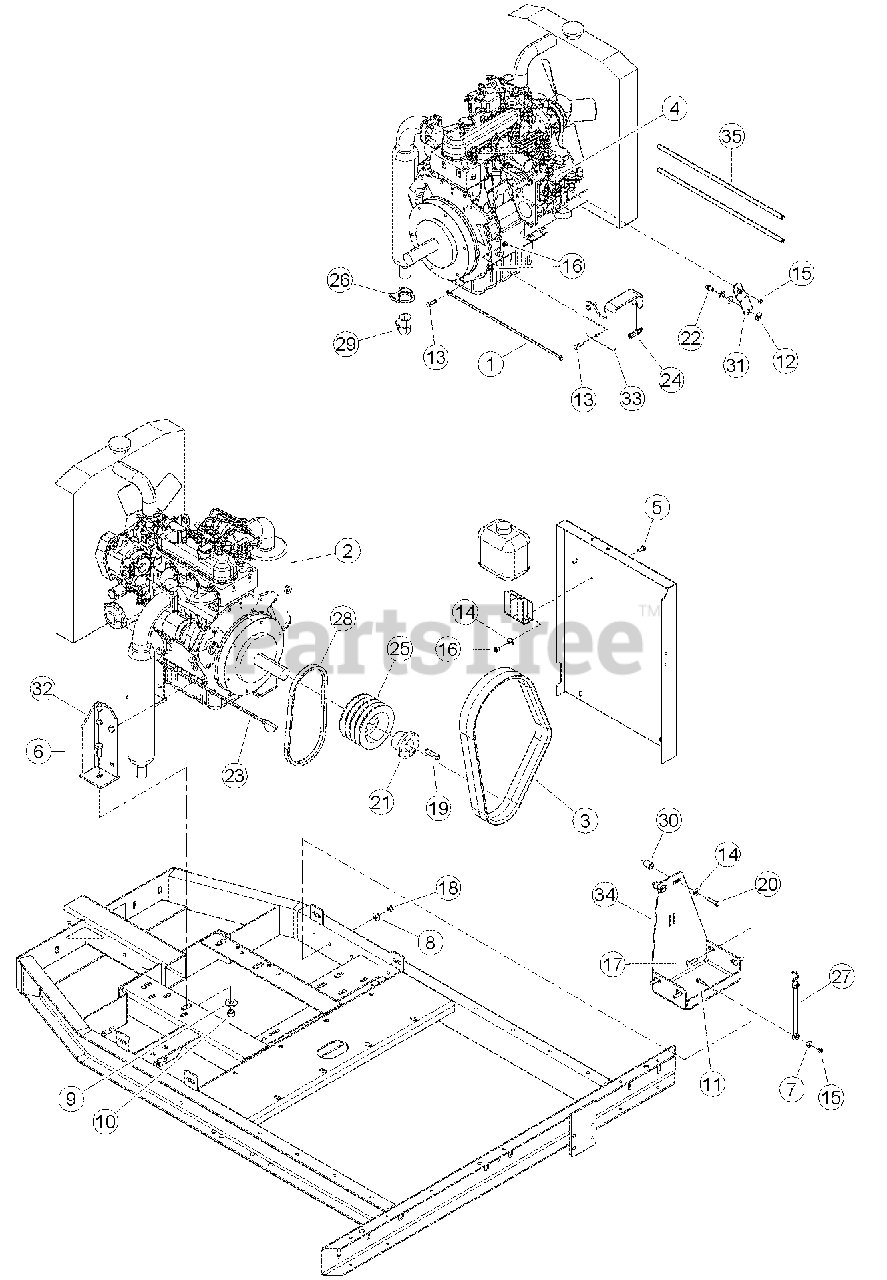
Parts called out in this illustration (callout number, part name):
1	CABLE, 18" NEG (R / R)
2	ENGINE, 1105B KUBOTA DIESEL (FOR SERVICE SEE ENGINE OWNERS MANUAL OR YOUR NEAREST KUBOTA INDUSTRIAL ENGINE DEALER.)
3	BELT, 3RB48 ARAMID
4	BOLT, 1/4 X 3/4 HEX HD GR5 ZP
5	BOLT, 5/16 X 3/4 HEX HD GR5 ZP
6	BOLT, 1/2 X 1-1/4 HEX HD GR5 NC ZP
7	WASHER, 1/4 FLAT ZP
8	WASHER, 3/8 FLAT ZP
9	WASHER, 1/2 FLAT ZP
10	NUT, 1/2 CENTERLOCK GRB ZP
11	BOLT, 1/4 X 1-1/4 HEX HD GR5 ZP
12	WASHER, 7/16 SAE FLAT ZP
13	BOLT, 5/16 X 1 HEX HD GR5 NC ZP
14	WASHER, 5/16 FLAT ZP
15	NUT, 1/4 NE NYLOCK ZP
16	NUT, 5/16 NE NYLOCK ZP
17	BOLT, 3/8 X 1-1/4 CRG GR5 NC ZP
18	NUT, 3/8 NE NYLOCK ZP
19	KEY, 3/8 SQUARE X 2 LONG PLAIN
20	BOLT, M8 X 1.25 X 40 GR8.8 HCPS
21	BUSHING, SD 1-7/16"
22	CABLE STOP - BOWDEN PIN # 6170
23	CABLE, 33" POS (R / R WITH BOOT)
24	BULKHEAD FITTING
25	SHEAVE, 4B5.2 SD
26	CLAMP, 1-1/2" MUFFLER
27	STRAP, 10 INCH TARP
28	BELT, BX30
29	ELBOW, KUBOTA EXHAUST
30	SPACER .75 X .90
31	STRIP, THROTTLE CONTROL
32	WELDMENT, ENGINE MOUNT
33	BRACKET, THROTTLE
34	PLATE, BATTERY/AIR CLEANER
35	HOSE, 20" FUEL
